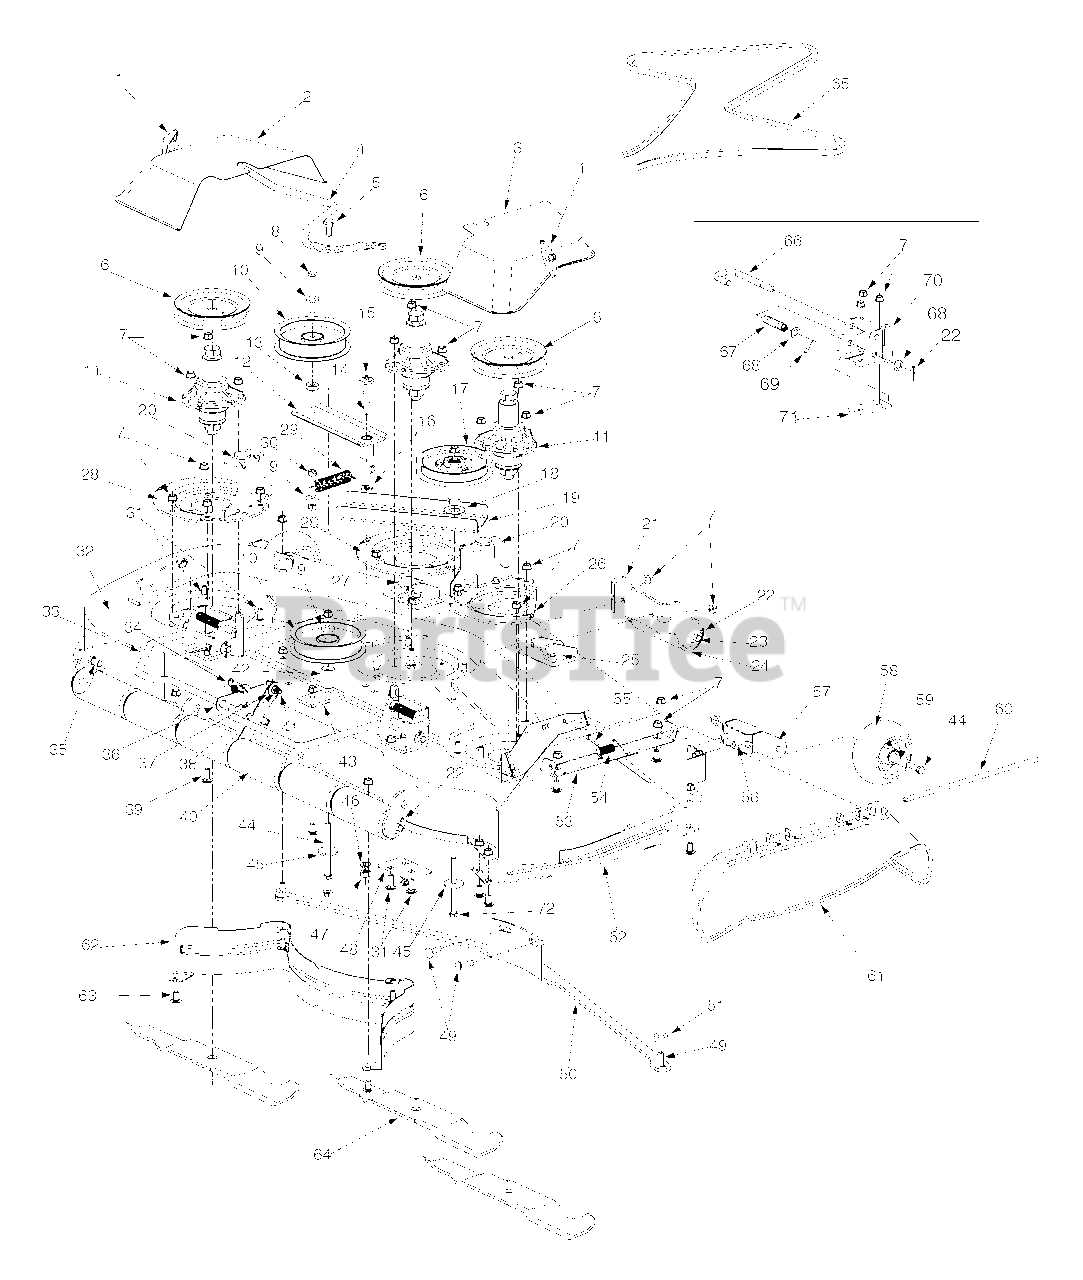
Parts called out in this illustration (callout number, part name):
1	Wingnut Knob
5	Shoulder Screw 3/8-16
6	Pulley
7	Flange Lock Nut 3/8-16
8	Hex Cap Screw 3/8-16 x 3.0
9	Flat Washer .385 ID x 1.0 OD
10	Idler Pulley 5.0
11	Deck Spindle Ass'y
14	Shoulder Bolt
15	Grease Fitting
16	Flat Washer .469 ID x .875 OD
17	Idler Pulley Ass'y 5.0
18	Flat Washer .78 ID x 1.59 OD
22	Cotter Pin
23	Roller Pin
30	Lock Nut 3/8-16
31	Carriage Bolt 3/8-16
34	Extension Spring .50 OD x 2.51 Lg
35	Pin Roller
38	Flange Lock Nut 5/16-18
39	Carriage Bolt 3/8-16
41	Shoulder Screw
45	Flat Washer
46	Lock Washer 7/16
47	Hex Nut 7/16-14
54	Torsion Spring
55	Cable Tie
56	Hex Cap Screw 3/8-16 x .880
60	Hinge Pin
61	Deflector Chute
63	Carriage Bolt 3/8 - 16
65	Belt 365 (161.00 LG)
66	Support Pin
67	Compression Spring
68	Flat Washer .536 ID x .93 OD
69	Spring Pin
